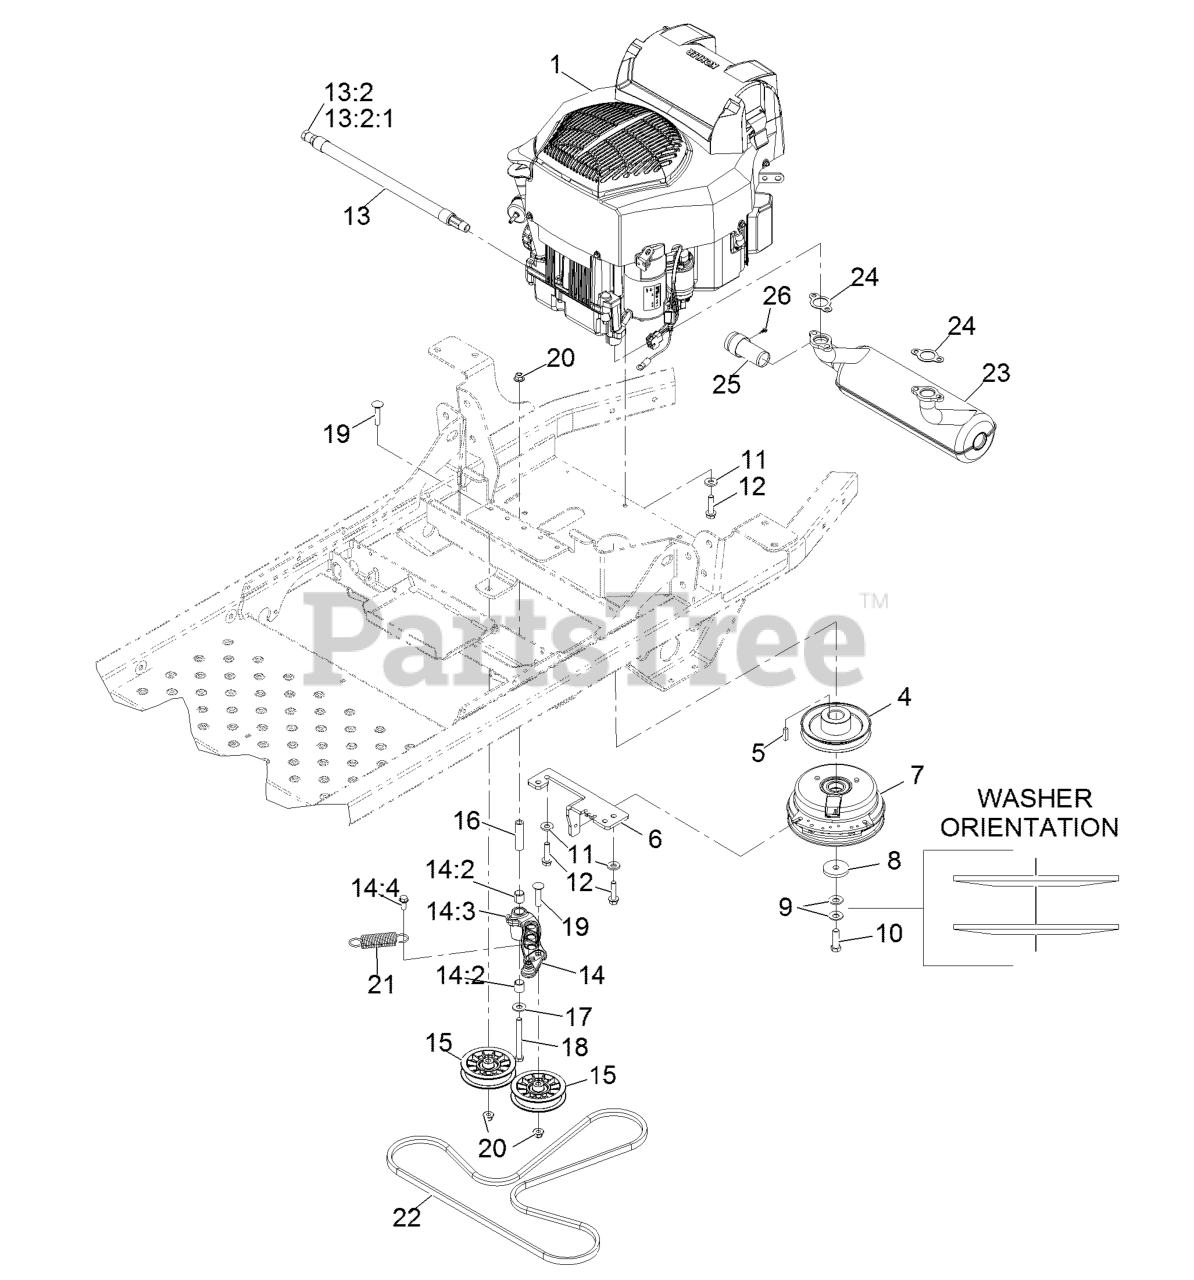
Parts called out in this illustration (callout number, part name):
4	SHEAVE-PUMP, DRIVE
6	ANCHOR-CLUTCH
8	WASHER-CLUTCH
9	WASHER-SPRING
10	SCREW-HH 7/16-20 X 1 1/2 W/LOCTITE
11	WASHER-BELLEVILLE
12	SCREW-HWH
13	OIL DRAIN HOSE ASM
13:2	PLUG-HH
13:2:1	O-RING
14	IDLER ARM ASM
14:2	SLEEVE-BEARING
14:3	FITTING-GREASE, 90 DEG
14:4	SCREW-THD ROLL, HWH
15	PULLEY-FLAT IDLER
16	BUSHING-PIVOT, IDLER
17	WASHER-FLAT
18	SCREW-CARR
19	SCREW-CARR
20	NUT-HF, NI
21	SPRING-EXTENSION
22	V-BELT
23	MUFFLER, KOHLER
24	GASKET-EXHAUST
25	ARRESTOR-SPARK
26	SCREW-HWH
